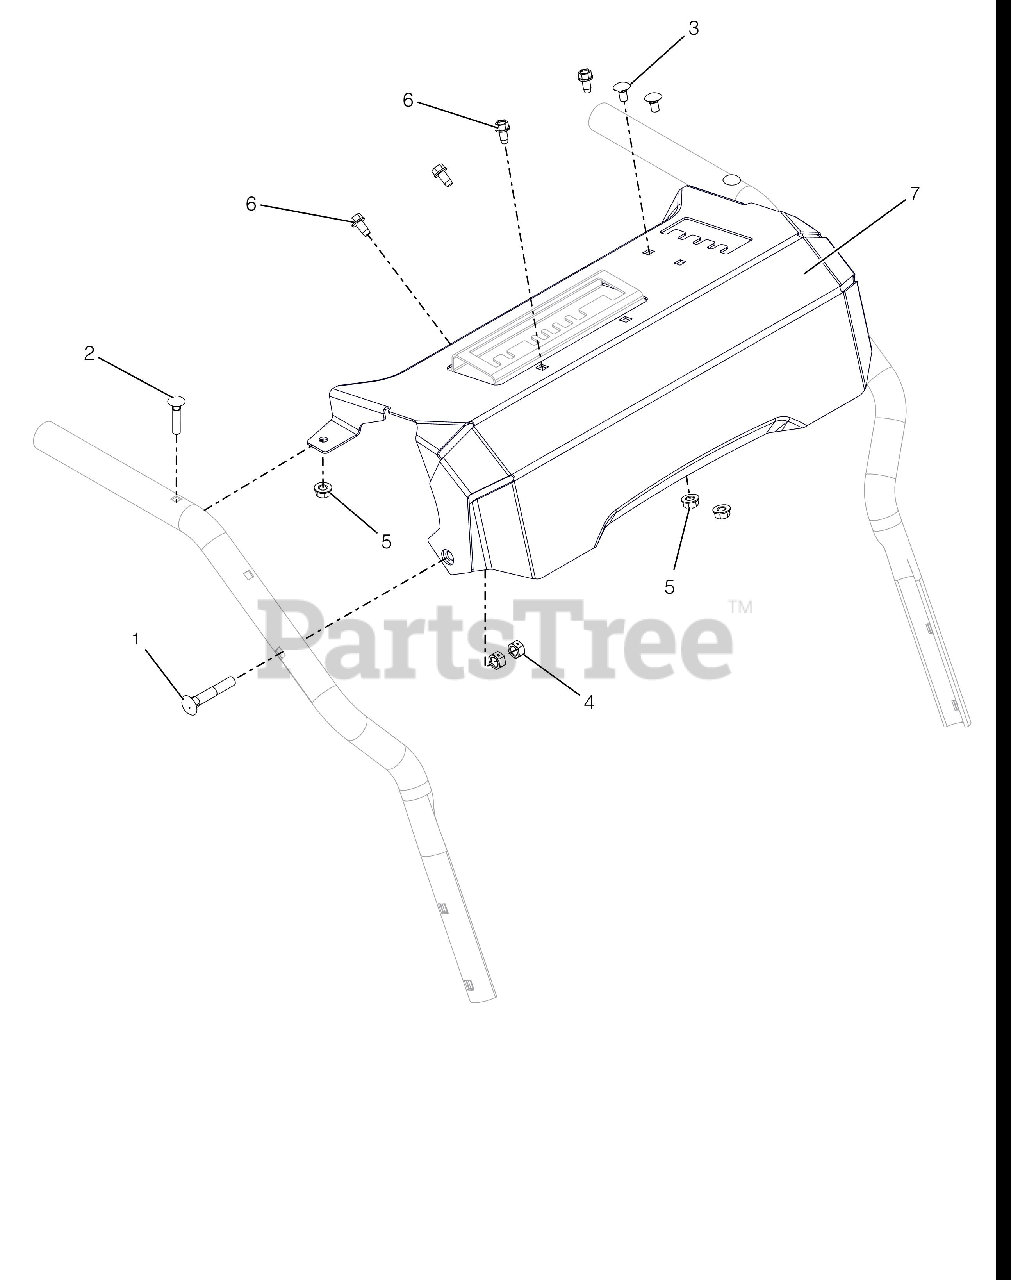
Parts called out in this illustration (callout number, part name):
1	BLT-RDHDXLSQNK .31-18X2.0 G5YZ
2	BLT-RDHDXLSQNK.25-20X1.25 G5ZC
3	@BLT-RDHDSQNK .25-20X.50 G5YZ
4	@NUT-LK-CTR .31-18 YWZC
5	@NUT-LK-TOP-FLG .25-20 YWZC
6	SCR-TAP .25-20X.50 HWH TR YWZ
7	CTRL PANEL W/DECAL-SNOTEK REMO
